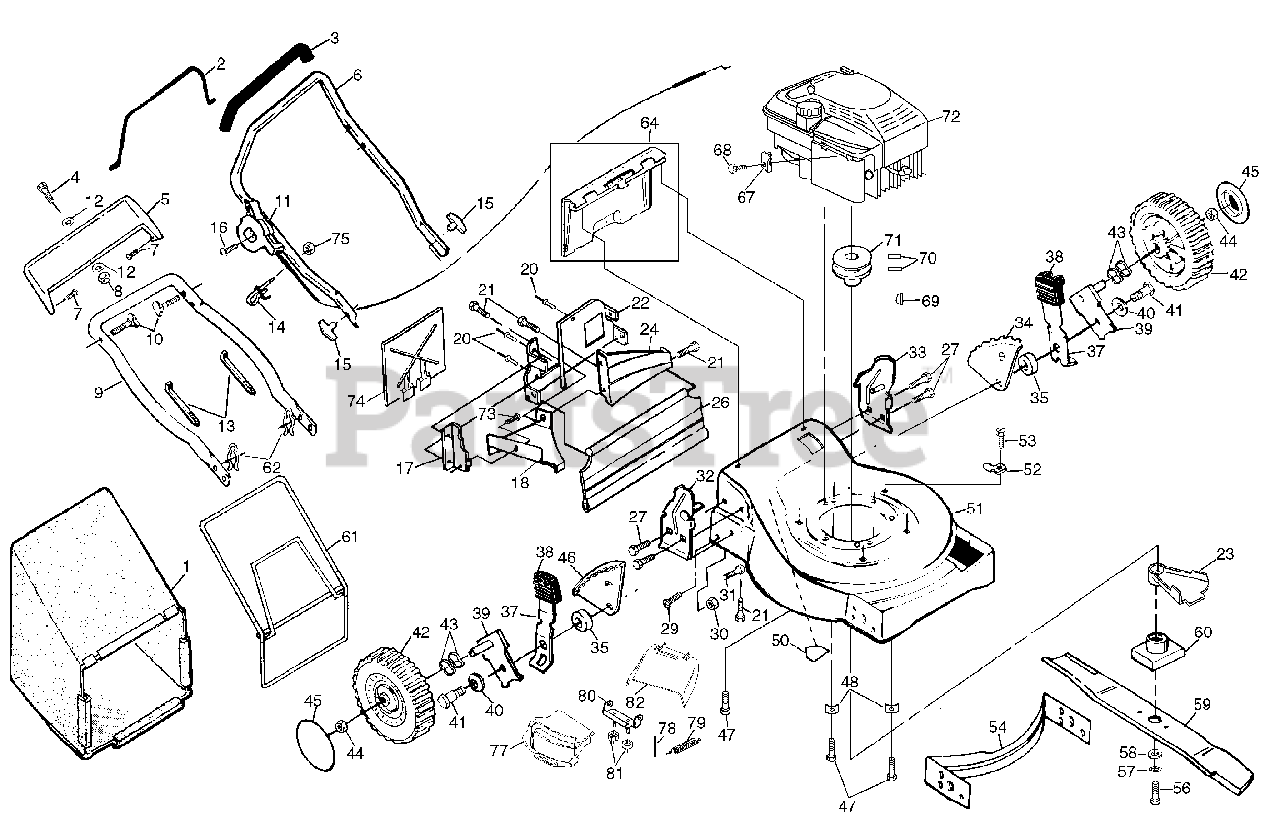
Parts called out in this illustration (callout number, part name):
1	Grass Bag Assembly
2	Control Bar
3	Handle Grip
4	Hex Washer Head Machine Screw 1/4-20 x 1-1/2
5	Trim Plate
6	Upper Handle
7	Self-tapping Screw #10-24 x 5/8
8	Locknut 1/4-20
9	Lower Handle
10	Handle Bolt
11	Throttle Control
13	Wire Tie
14	Rope Guide
15	Handle Knob
16	Round Head Screw 1/4-20 x 2-3/4
17	Side Baffle
18	Discharge Baffle
21	Hex Tapping Screw 1/4-20 x 1/2
22	Back Plate
23	Debris Shield
24	Rear Baffle
26	Rear Skirt
27	Thread Cutting Screw 5/16-18 x 3/4
29	Hinge Screw
30	Locknut
32	Handle Bracket Assembly (Right)
33	Handle Bracket Assembly (Left)
34	Wheel Adjusting Bracket (LR)
35	Spacer
37	Selector Spring
38	Selector Knob
39	Axle Arm Assembly
40	Belleville Washer
41	Shoulder Bolt 3/8-16
42	Wheel & Tire Assembly
43	Wave Washer
44	Nut
46	Wheel Adjusting Bracket (RR)
47	Thread Rolling Screw 3/8-16 x 1
48	Engine Washer
50	Danger Decal
51	Lawn Mower Housing
52	Guide Clip (Housing)
53	Hex Washer Head Screw #10-24 x 1/2
54	Front Baffle
56	Hex Head Screw 3/8-24 x 1-3/8 Gr. 8
57	Helical Lockwasher 3/8
58	Hardened Washer
60	Blade Adapter
61	Catcher Frame Assembly
62	Hairpin Cotter
64	Rear Door Assembly
67	Cable Clamp
68	Thread Rolling Screw #10-32 x 5/8
69	Hi-Pro Key
70	Set Screw 1/4-20 x 5/16
71	Engine Pulley
74	Mulcher Plate
75	Keps Locknut
77	Mulcher Door
79	Hinge Spring
80	Hinge Bracket
81	Nut
82	Clip-on Discharge Guard
